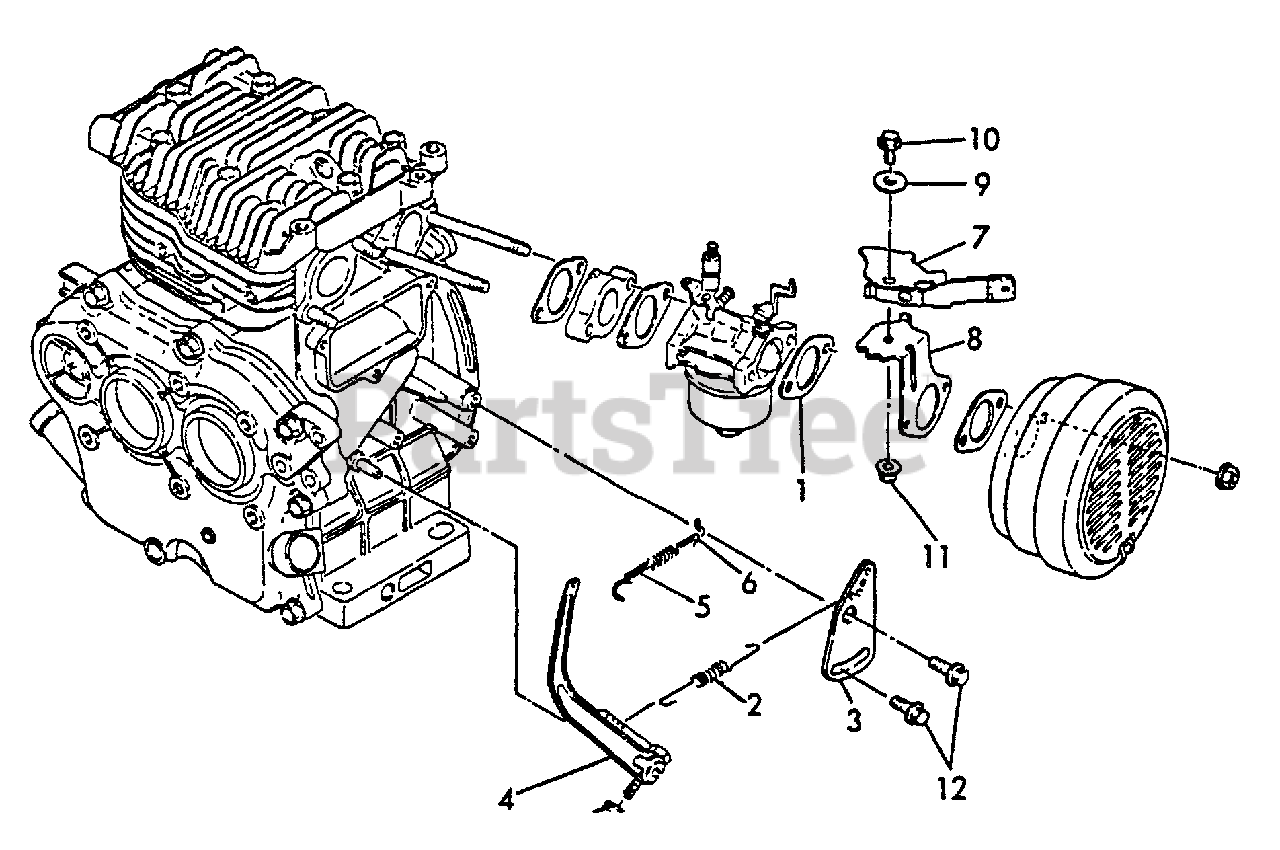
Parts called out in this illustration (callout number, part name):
2	SPRING, REGULATOR
3	HANDLE, REGULATOR
4	LEVER, GOVERNOR
5	LINK, THROTTLE
6	SPRING, TENSION
7	LEVEL ASSY
8	BRACKET, LEVER
9	COLLAR
10	BOLT - 6×12 -- PLATED
11	U-NUT M6
12	BOLT - 6×8 -- PLATED
